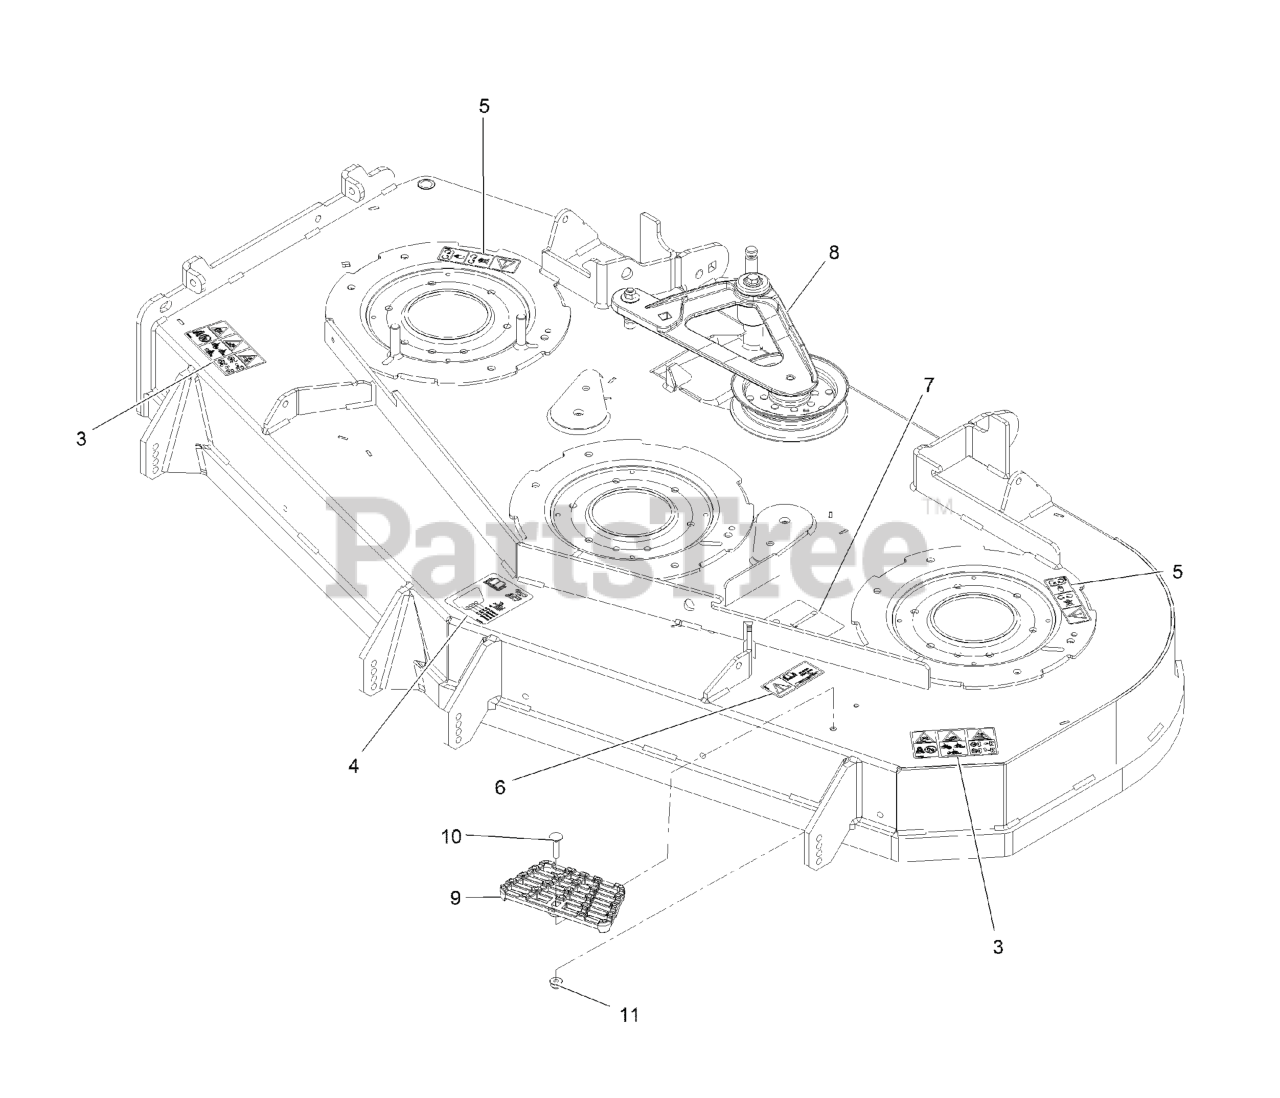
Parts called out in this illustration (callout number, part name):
3	DECAL-DANGER THROWN OBJECTS
4	DECAL-ROLLER, ANTI-SCALP
5	DECAL-COVER, MISSING
6	DECAL-TORQUE, BOLT
7	DECAL-BELT ROUTING
8	DECK IDLER ASM
9	STEP-DECK
10	Bolt-Carriage 5/16-18 X 1 1/4
11	NUT-HF, NI
